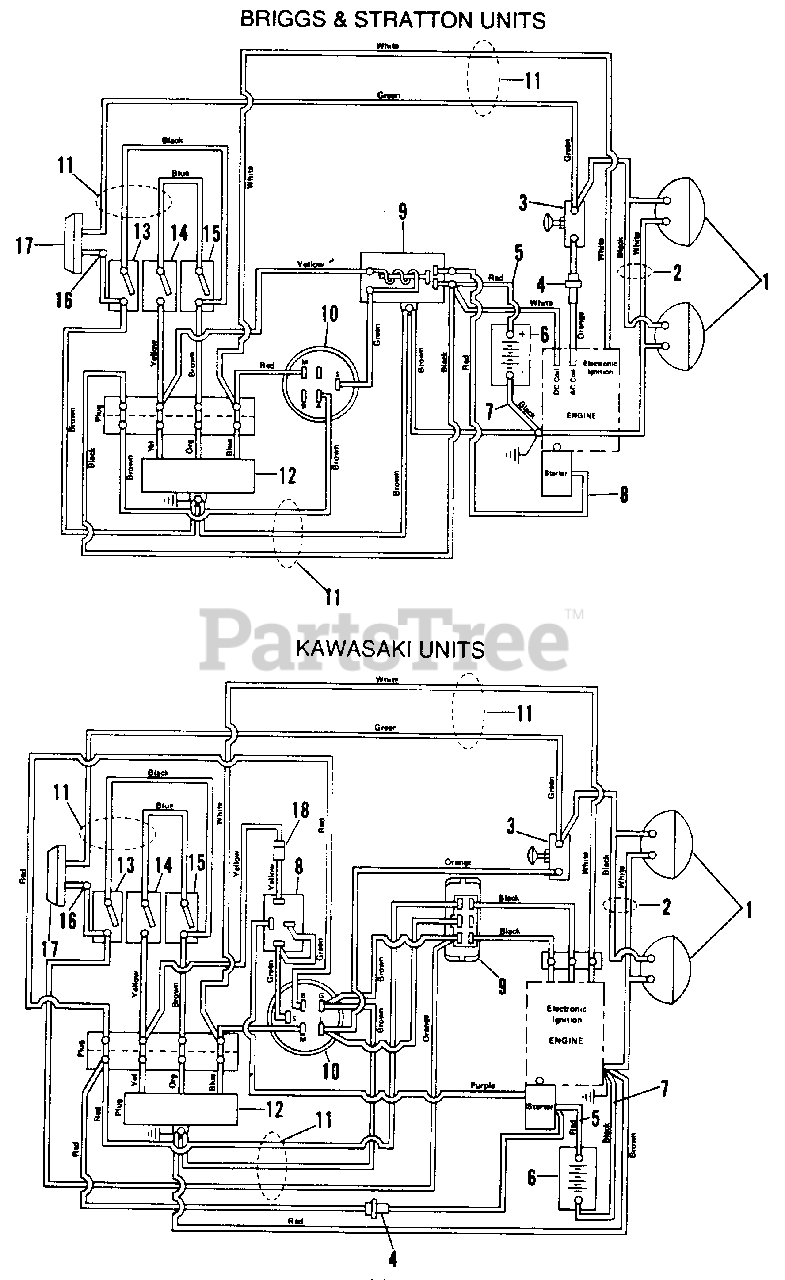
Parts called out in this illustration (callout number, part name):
1	HEADLIGHT
2	HARNESS, HEADLIGHT WIRING
3	SWITCH, LIGHT
4	FUSE, 6 AMP
4	FUSE, 15 AMP
5	CABLE, 10" STARTER
5	CABLE
6	BATTERY
7	CABLE, 46" GROUND
8	CABLE, 43"
9	SOLENOID
10	ASSEMBLY, IGNITION SWITCH AND KEY
11	HARNESS, WIRING, B&S
12	MODULE(W/CONNECTOR)
13	SWITCH, SEAT
14	SWITCH, INTERLOCK
15	SWITCH
16	CLIP, ADAPTER
17	ASSEMBLY, TAIL LIGHT
NS	BOOT, BATTERY CABLE
